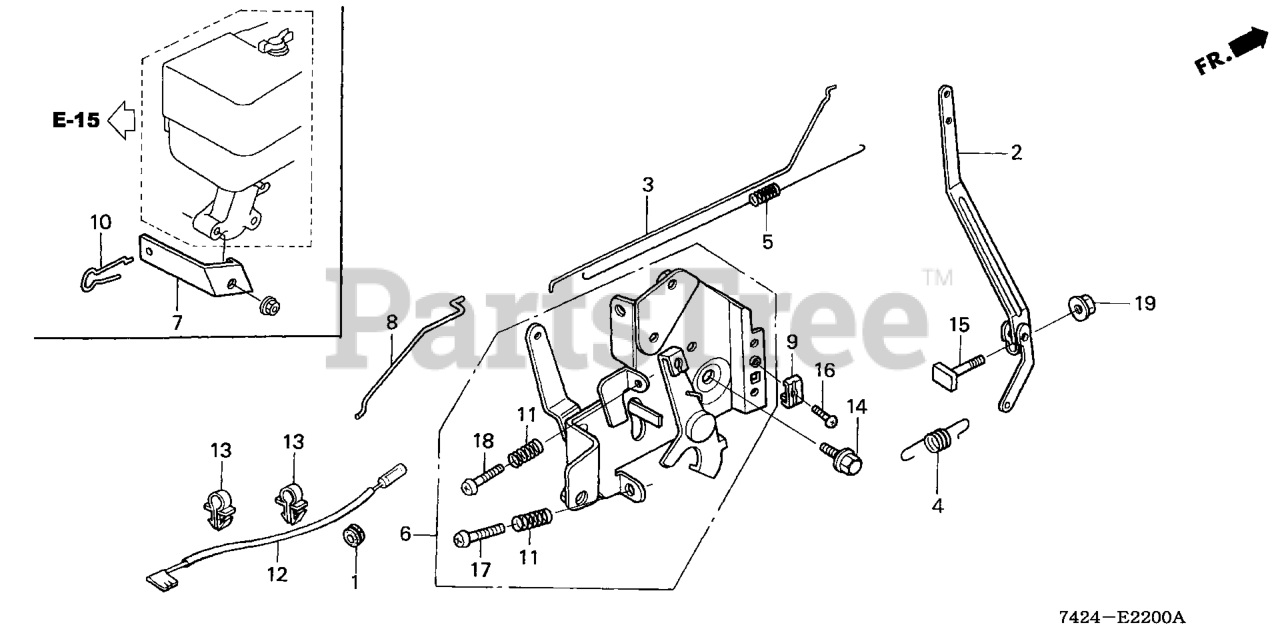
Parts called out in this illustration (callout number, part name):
1	GROMMET, ADJUSTING COVER
2	ARM, GOVERNOR
3	ROD, GOVERNOR
4	SPRING, GOVERNOR
5	SPRING, THROTTLE RETURN
7	STAY, CHOKE
9	HOLDER, CABLE
10	PIN, CHOKE
11	SPRING, CONTROL ADJUSTING Use from Engine SN 2327377.
12	WIRE, STOP SWITCH
13	HOLDER, STOP SWITCH WIRE Use up to Engine SN 2056819.
14	BOLT, FLANGE (6X12) (CT200)
15	BOLT, GOVERNOR ARM
16	SCREW, PAN (5X16)
17	SCREW, PAN (5X20)
18	SCREW, PAN (5X25)
19	NUT, FLANGE (6MM)
